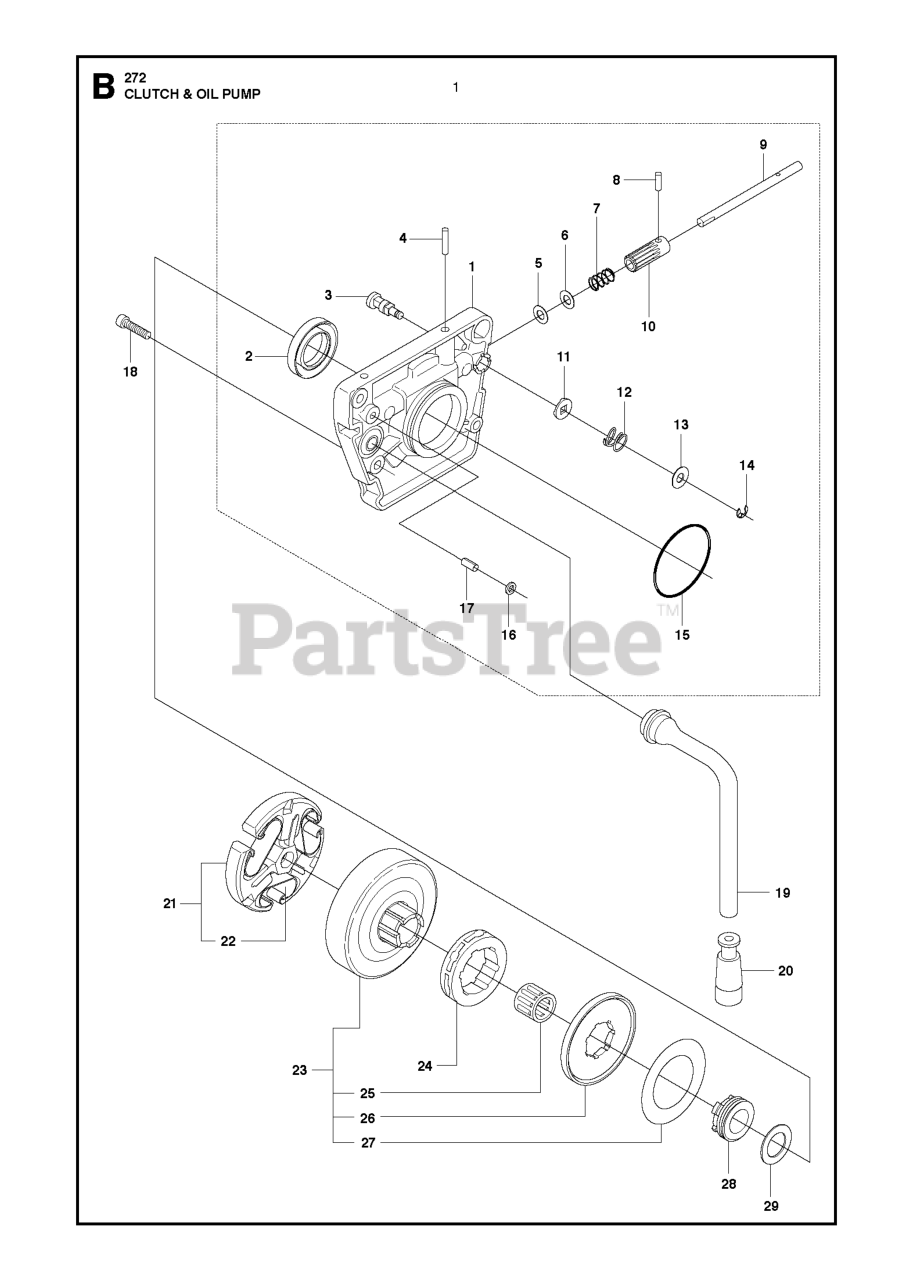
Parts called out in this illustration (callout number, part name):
1	DECK 52" FAB WELDMENT ORANGE
2	SEALING RING
2	MANDREL.DECK.ASSEMBLY
3	CONTROL SCREW
3	WASHER.SPACER.MANDREL
4	PARALLEL PIN 3X18
4	PULLEY.DRIVEN.DECK.48'
5	WASHER 5.1X8.5
5	NUT.FLANGE.LOCK.TOP
6	WASHER 5.1X8.5
6	SCREW, WASHER HEAD
7	DISCHARGE CHUTE 52"
8	SPRING - TORSION
9	PIN-CLEVIS 5/16 DIA X 5.19 ZD
10	GEAR WHEEL
10	BLADE, 17.75 X 2.5 X .25
11	BOLT.WASHER.ASM.7/16-2
12	PLATE, 52" CONF. BLK
13	BOLT.CARR.5/16-18X5/8.SHORT
14	E-RING 3.2
14	NUT.71038.31-18.HEX.NYLOCK
15	STUD.FASTNER.W/ANTI-ROTATE
16	5/16-18 NYLOC FLANGE NUT
17	SPRING PIN 3X6
17	PULLEY.IDLER.MWR.STATI.LH
18	SCREW MC6S 4X16
18	ARM, IDLER, 52" BLK
19	PULLEY.IDLER.FLAT
20	OIL SCREEN
20	PULLEY, IDLER
21	BUSHING, IDLER
22	WHEEL GAGE DONUT
23	CLUTCH DRUM ASSY
23	CLUTCH DRUM
23	BOLT.SHOULDER.3/8-16X3-5/8.
24	22273 Sprocket 3/8"x8T
24	68210 RIMSPROCKET
24	NUT 3/8-16 HEX FLG NYLOC ZD
25	SUPPORT BUSHING
25	SHIELD.BELT.LH.ORANGE
26	DUST PROTECTION
27	U-CLIP 5/16-18 NUT RETAINER
28	WORM WHEEL
28	HCS 3/8-16 X 3-1/2 GR5 ZD
29	WASHER 13.1X20
29	SPINDLE WASHER
30	RP WASHER 3/8 FLAT
31	NUT 3/8-16 NYLOC
32	RHSNB 3/8-16X1-3/4
33	WASHER 7/16 FLAT ZD
35	NUT.LOCK.FLANGE.7/16
36	ARM.SUSPENSION.MOWER
37	SB 3/8-16 X 3/8 SKT HD ZD
38	WASHER
39	NUT HEX 3/8-16 NYLON, THIN
40	NOSE ROLLER 48"
41	ROD.ROLLER.NOSE.NARROW.48"
42	PIN.COTTER.5/16.BOW TI
43	WASHER.5/16.FLAT.STE.STD.
44	SHIELD.BELT.RH.52.ORANGE
45	BOLT.FIN.HEX.5/16-18UNC X 1.00
46	WASH.5/16.SLW.ZD
50	PORT.WASHOUT
51	SCREW
52	BOLT.HEX.7/16-14
53	BELT, 143.5" EL
54	GUARD, BELT
55	EYE BOLT 5/16 X 3.50
56	NUT 5/16C WHIZ
59	RP PULLEY, COLLECTION 48
60	RETAINER CLIP
61	ROD.ANTI.SWAY.48/54"TE
62	WASHER
